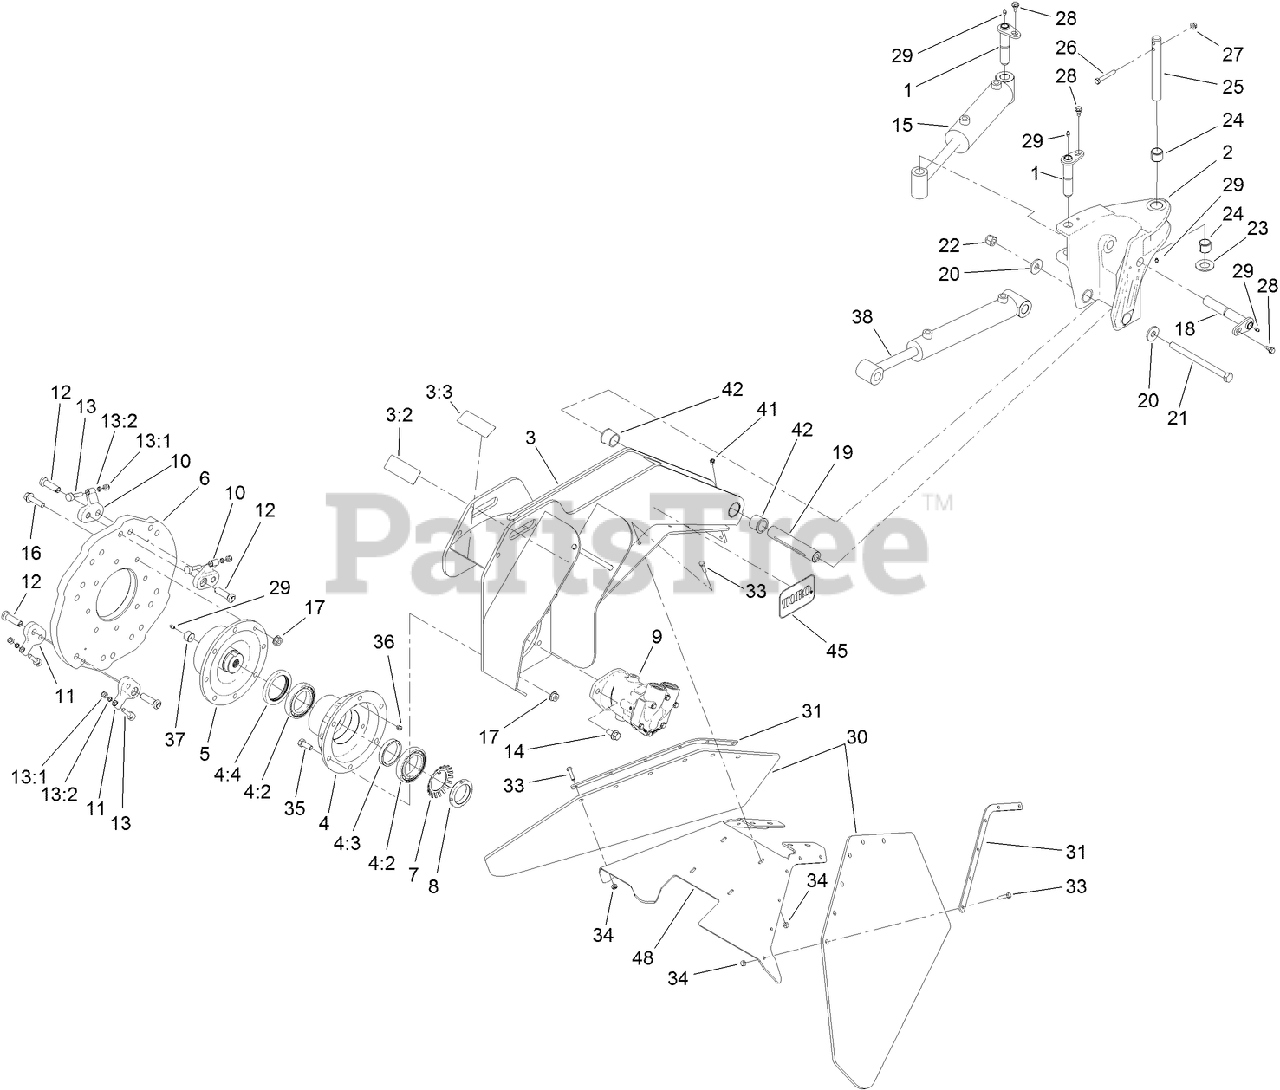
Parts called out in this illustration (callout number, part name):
1	PIN-PIVOT
2	HEAD-PIVOT
3	GRINDER HEAD ASM
3:2	DECAL-DANGER
3:3	DECAL-WARNING
4	WHEEL BEARING HOUSING ASM
4:2	BEARING-BALL
4:3	SPACER-BEARING
4:4	SEAL-GREASE
5	SHAFT-CUTTER
6	PLATE-WHEEL, CUTTER
7	WASHER-LOCK, BEARING
8	NUT-LOCK, BEARING
9	HYD MOTOR ASM
10	POCKET-ANGLED
11	POCKET-STRAIGHT
12	BOLT-HSH
13	GRINDER TOOTH ASM
13:1	NUT-LOCK, NI
13:2	SPACER-TOOTH
14	SCREW-HHF
15	HYD CYLINDER ASM
16	SCREW-HHF
17	NUT-HHF
18	PIN-PIVOT
19	SPACER-PIVOT
20	WASHER-HARDENED
21	BOLT-HH
22	NUT-LOCK, NI
23	WASHER-THRUST
24	BUSHING-TENSION
25	PIN-PIVOT, GRINDER
26	SCREW-HH
27	NUT-HHF, WHIZ
28	BOLT-SHOULDER
29	FITTING-GREASE
30	SHIELD-CHIP
31	PLATE-CLAMP,CHIP
33	SCREW-HH
34	NUT-LOCK, NI
35	SCREW-HH
36	FITTING-LUBE
37	PLUG-SHAFT, CUTTER
38	HYD CYLINDER ASM
41	FITTING-LUBE, 45 DEG
42	BUSHING-FLANGE
48	PLATE-MOUNT,GUARD
